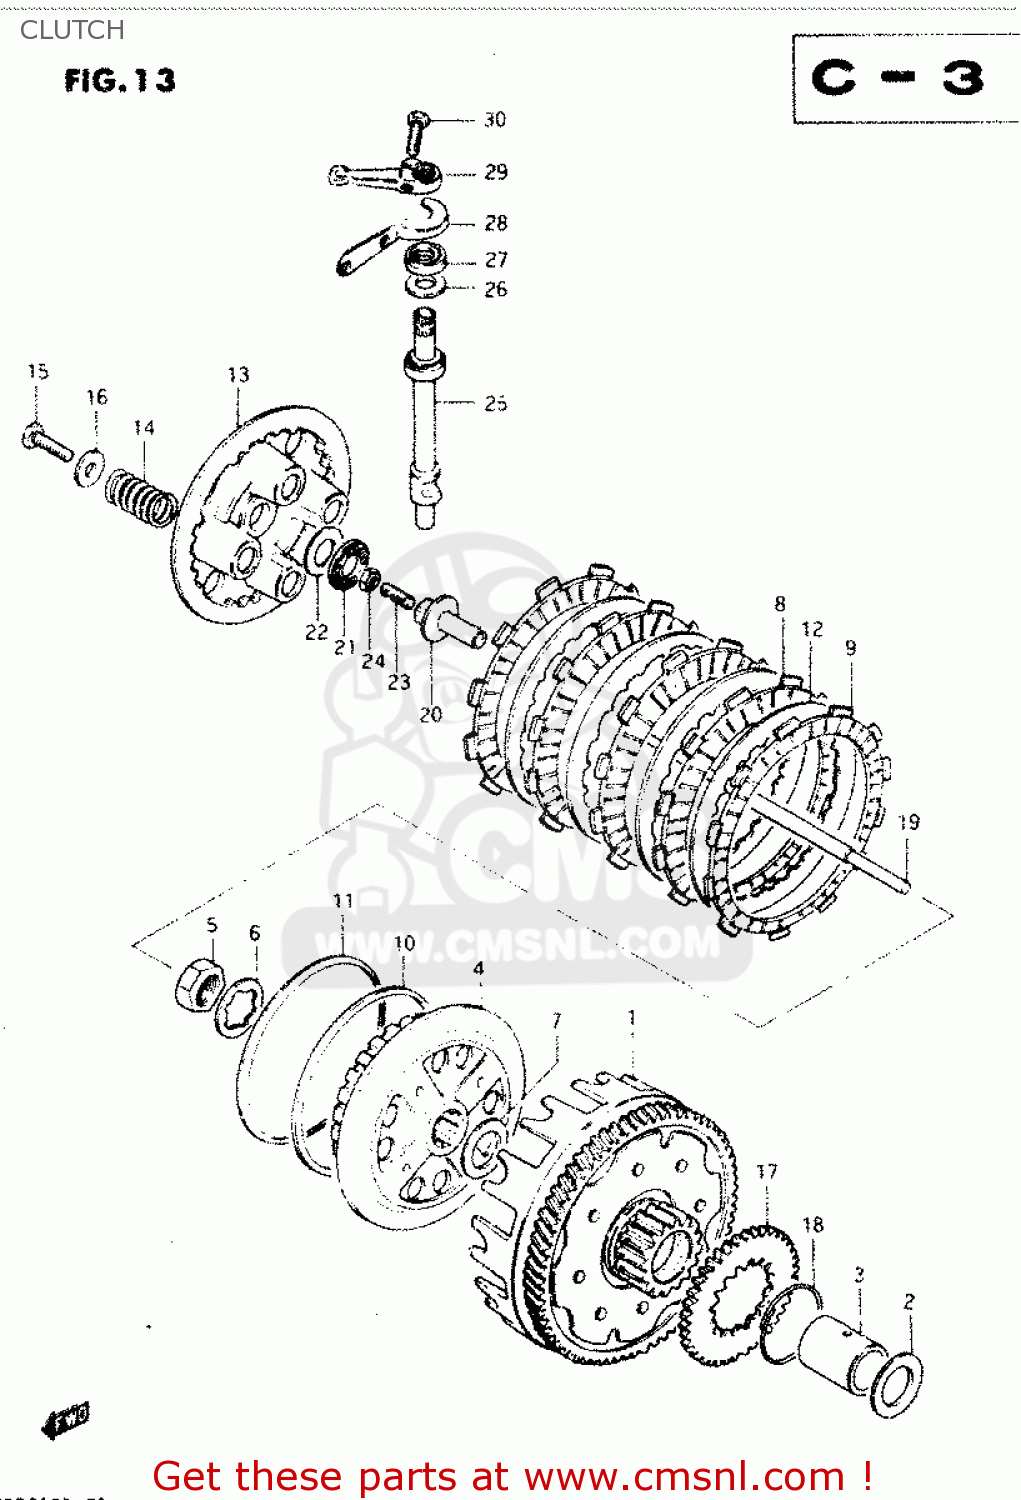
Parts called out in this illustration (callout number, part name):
1	GEAR ASSEMBLY,PRIMARY DRIVE
2	WASHER
3	SPACER(22X28X37.5)
4	HUB,CLUTCH SLEEVE
5	NUT
6	WASHER,LOCK
7	WASHER
8	PLATE,CLUTCH DRIVE (MCA)
9	PLATE,CLUTCH DRIVE
10	SEAT,WAVE WASHER(T:1.4)
11	WASHER
12	PLATE,CLUTCH DRIVEN
13	DISC,CLUTCH PRESSURE
14	SPRING
15	BOLT, UPPER
16	WASHER
17	GEAR,OIL PUMP DRIVE
18	CIRCLIP
19	ROD,CLUTCH PUSH
20	PIECE,CLUTCH PUSH
21	BEARING(15X28X2)
22	WASHER
23	SCREW
24	NUT 6MM
25	CAMSHAFT,CLUTCH RELEASE
26	WASHER (14.2X22X1)
27	OIL SEAL
28	PLATE,RELEASE CAM SHAFT
29	ARM,CLUTCH RELEASE
30	BOLT
